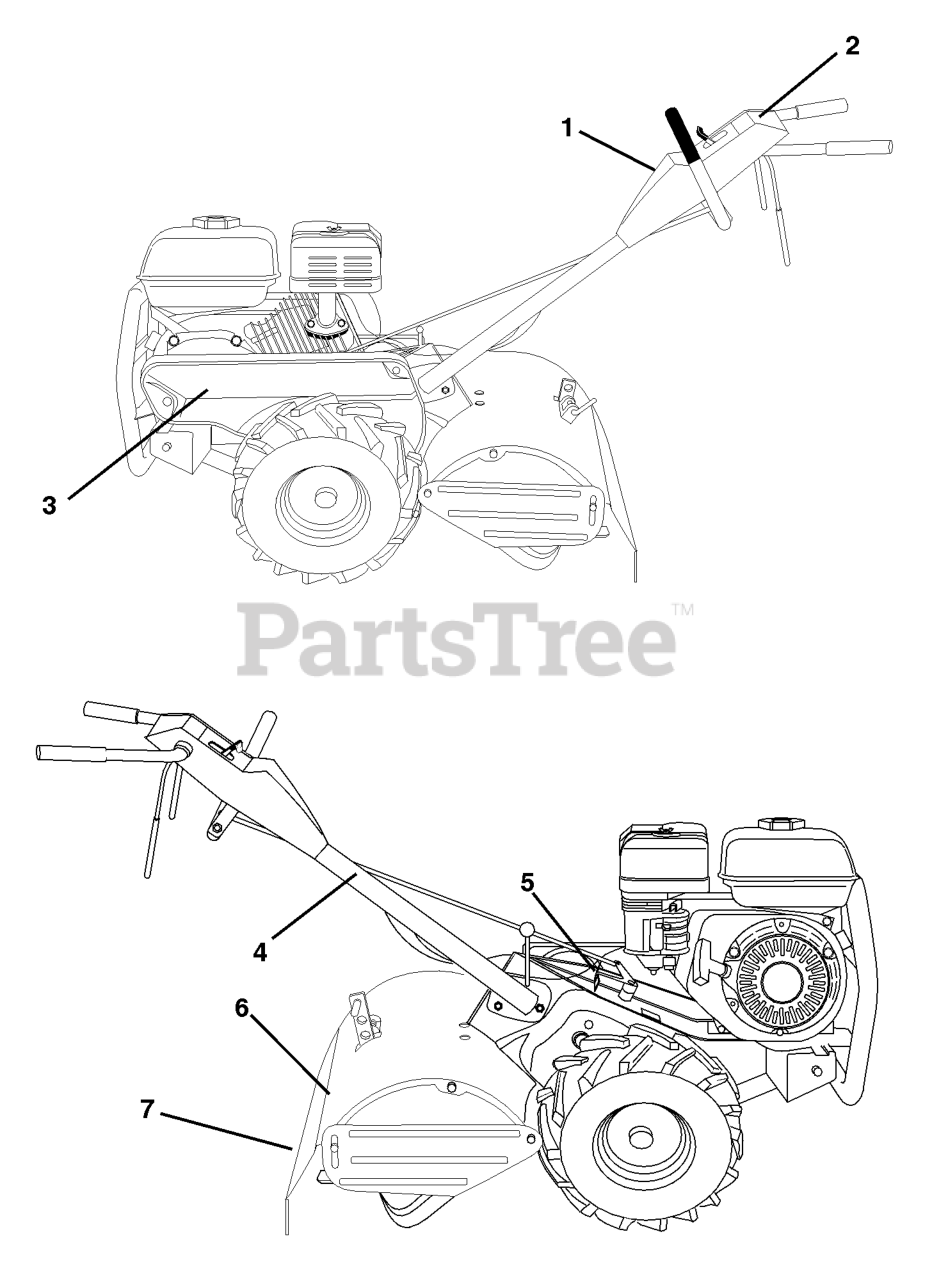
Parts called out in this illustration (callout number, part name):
1	DECAL, LOGO
2	DECAL, LOGO
3	Decal, Logo
4	DECAL TI (2 2)
5	DECAL.SHIFT.INDICATOR.TILLER
6	DECAL -CAUTION
7	DECAL TI
